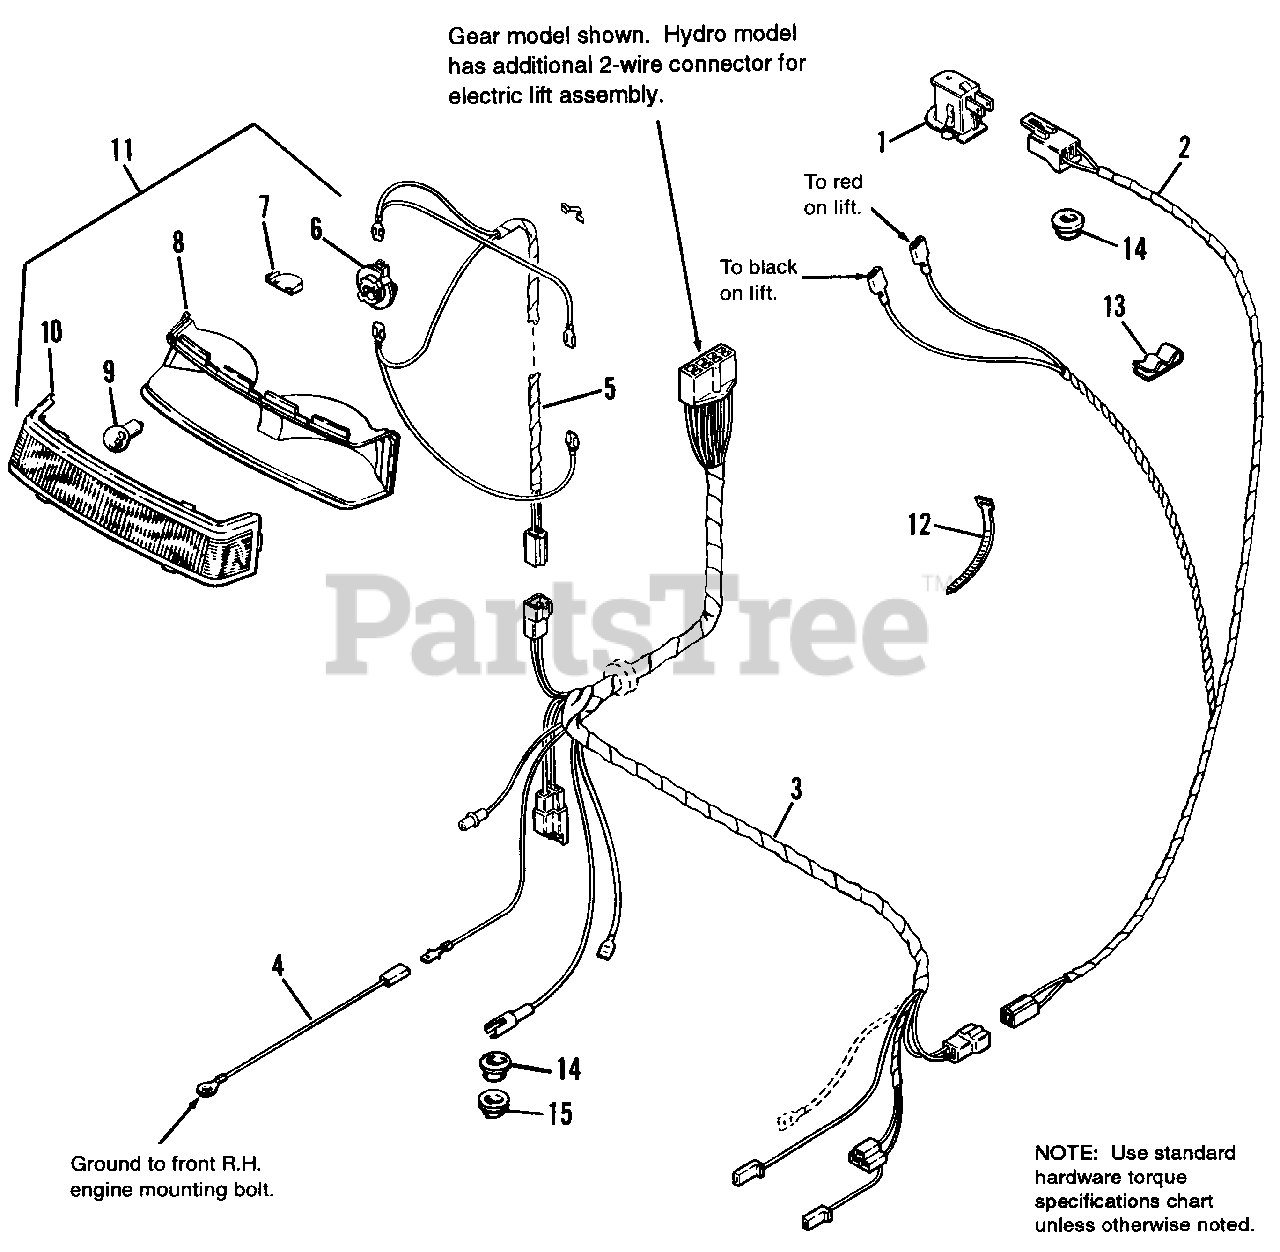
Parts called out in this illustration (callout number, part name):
1	SWITCH, Seat, Operator Present
2	WIRE ASSY., Seat Switch and Lift
3	HARNESS ASSY., Lower (All models except Mfg. Nos. 1692024, 1692033)
3	HARNESS ASSY., Lower (Mfg. Nos. 1692024, 1692033 Only)
4	WIRE ASSY., Engine Ground
5	WIRE ASSY., Headlight
6	SOCKET, Bulb
7	HEAT SHIELD
8	BEZEL, Headlight
9	BULB, Headlight ,12.8V
10	LENS, Headlight
11	HEADLIGHT ASSY. (Incl. Ref. Nos. 6-10)
13	CLIP, Speed
14	BUSHING, Snap, Small (Qty. 2 used on Briggs & Stratton engine)
15	BUSHING, Snap, Small (Kohler engine only)
